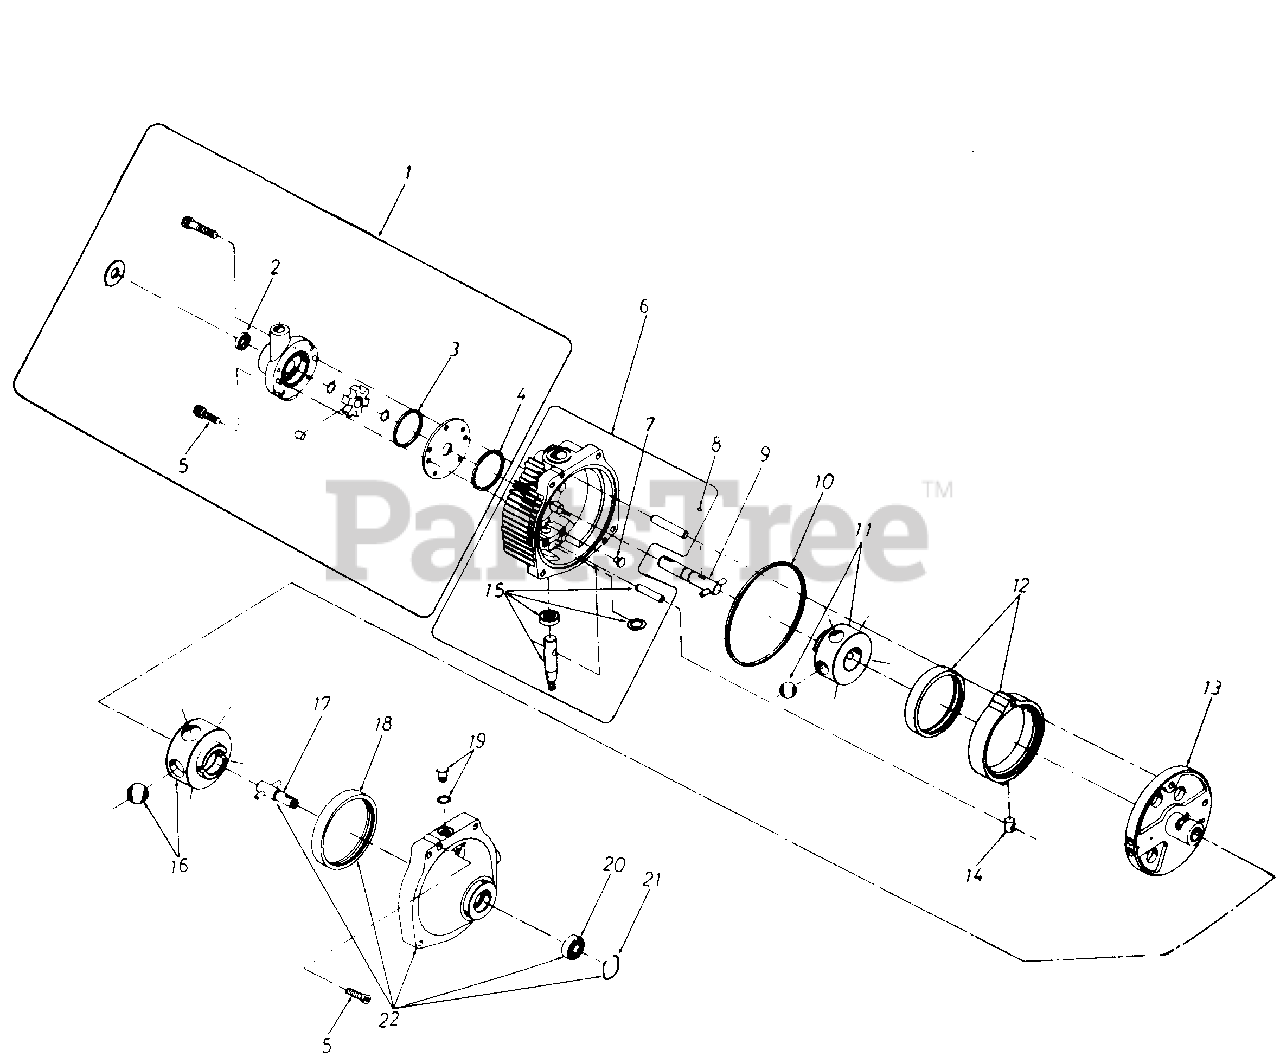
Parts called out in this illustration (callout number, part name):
1	Charge Pump Kit
2	Oil Seal
3	Square Cut Seal Ring .036
4	Square Cut Seal Ring .038
5	Socket Head Cap Screw 5/16-18 x 1.25" Long
6	Cover Subassembly
8	Drive Pin
9	Input Shaft Subassembly
10	Square Cut Seal Ring .166
11	Pump Rotor-Ball Subassembly
12	Cam Ring Subassembly
13	Pintle Subassembly
14	Cam Ring Insert
15	Control Shaft Kit
16	Motor Rotor-Ball Subassembly
17	Output Shaft Subassembly
18	Motor Race
19	"O"-Ring Plug Subassembly
20	Ball Bearing
21	Retaining Ring
22	Body Subassembly
